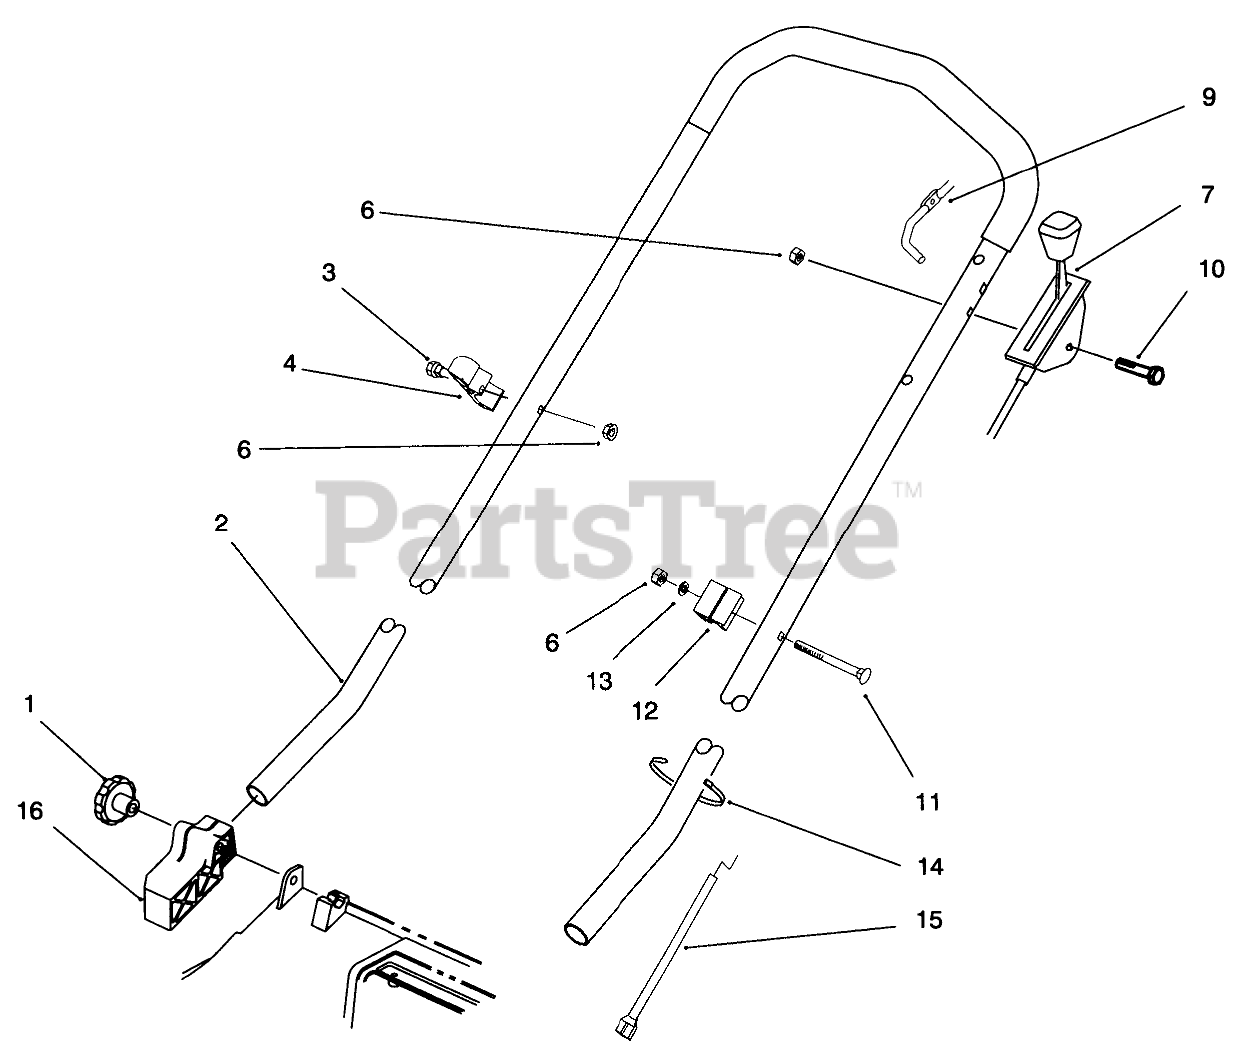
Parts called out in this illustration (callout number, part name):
2	HANDLE
3	.250-20X1.625 HH SCREW
4	GUIDE - ROPE
6	NUT-LOCK, NI
7	CONTROL - THROTTLE
9	Bail-Brake
10	SCREW-HH
11	SCREW-HANDLE
12	SUPPORT-CABLE
13	WASHER-FLAT
14	TIE-CABLE
15	CABLE - BRAKE
16	MOUNT-HANDLE, RH
